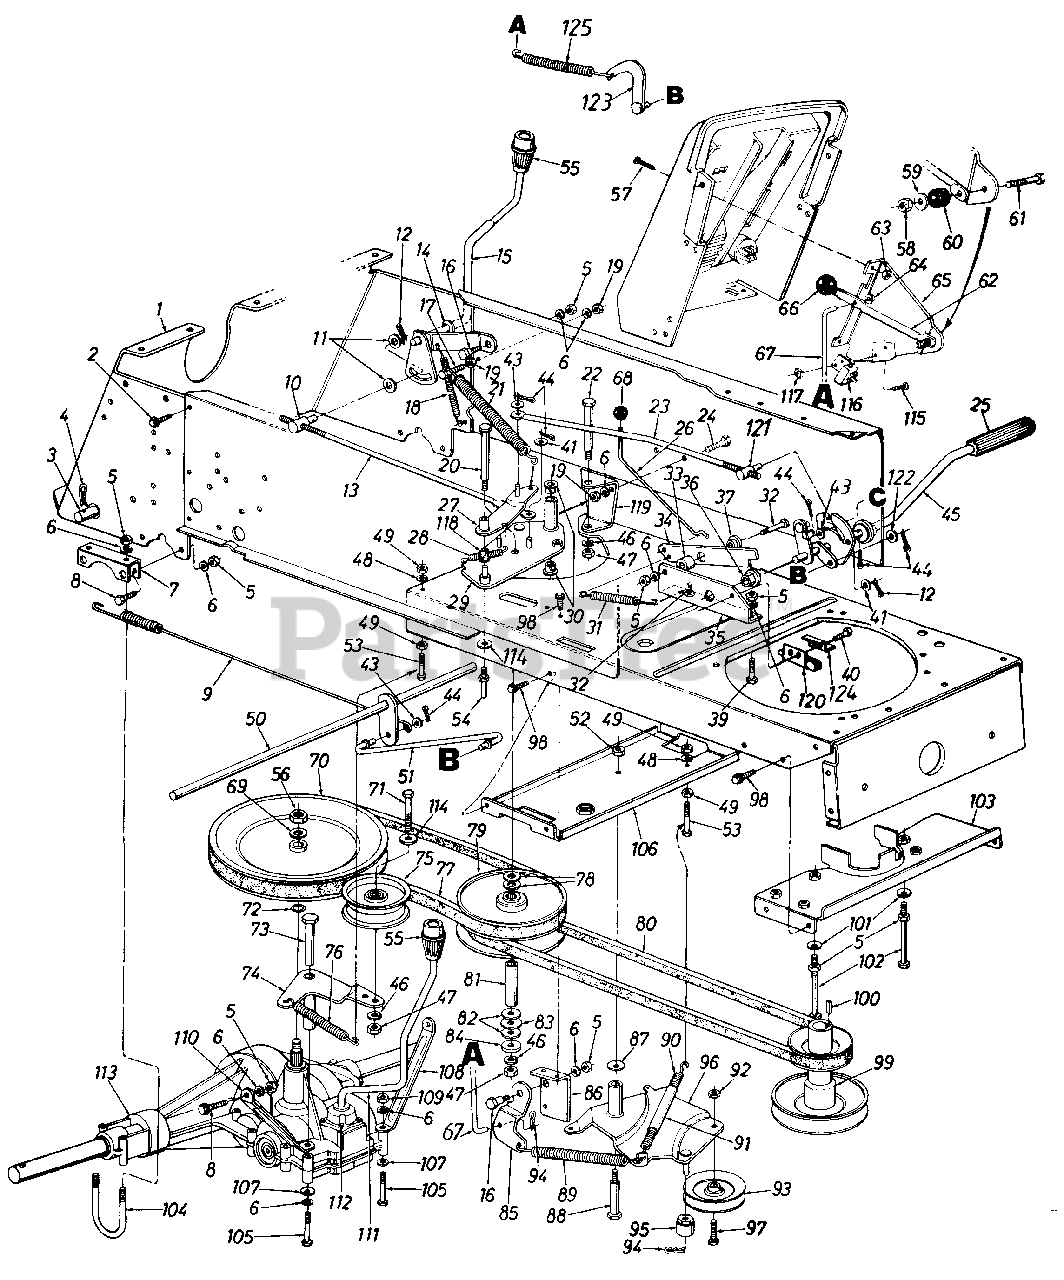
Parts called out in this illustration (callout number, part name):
4	Hitch Pin Clip
5	Hex Nut 5/16-18 Thd.
6	L-Wash. 5/16" I.D.
7	Transaxle Bracket
8	Hex Bolt 5/16-18 x .75" Lg. (Gr. 5)
9	Brake Extension Spring
10	Adjustment Ferrule 3/8-24 Thd.
11	Fl-Wash. .385" I.D. x .87"
12	Internal Cotter Pin
13	Speed Control Link
14	Fl-Wash. .531" I.D. x .94"
15	Speed Selector Lever Ass'y.
16	Shld. Bolt .437" Dia. x .162"
17	Hex Bolt 5/16-24 x 1.25" Lg.
18	Extension Spring 3.9" Lg.
19	Hex Nut 5/16-24 Thd. (Gr. 5)
20	Hex Bolt 3/8-24 x 4.5" Lg.
21	Extension Spring 11" Lg.
22	Shld. Bolt .625n Dia. x 3.5" Lg.
23	Speed Control Link
24	Hex Bolt 5/16-24 x .75" Lg.
25	Foot Pad
26	Parking Brake Link
29	Pulley Plate Ass'y.
30	Flanged Brg. .63" I.D.
31	Extension Spring 2.51" Lg.
32	Hex Bolt 5/16-18 x 1.25" Lg.*
33	Spacer .34" I.D. x .88"
36	Hex Flange Brg. .634" I.D.
37	Shld. Spacer .5" Dia.
39	Hex Bolt 5/16-18 x .75" Lg.
40	Hex Tap Scr. #10-32 x 5/8" Lg.
41	Fl-Wash. .406" I.D. x ,75n O.D.
43	Fl-Wash. .34" I.D. x .68" O.D.
44	Cotter Pin 3/32" Dia.
47	Hex Nut 3/8-24 Thd.
48	L-Wash. 1/4" I.D.
49	Hex Nut 1/4-20 Thd.
50	Brake Link Bracket
51	Front Brake Rod Link
52	Hex Cent. L-Nut 3/8-16 Thd.
53	Hex Bolt 1/4-20 x 2.0" Lg.
54	Belt Guard Pin
56	Hex Jam Nut 9/16-18 Thd.
57	Truss Mach. Scr. 1/4-20 x .5" Lg.
58	Hex Ins. L-Nut 1/4-20 Thd.
59	Fl-Wash. .28" I.D. x .73" O.D.
60	Rubber Washer .33" I.D.
61	Hex Bolt 1/4-20 x 1.25n Lg.
62	Blade Clutch Lever
63	Hex Sems Nut 1/4-20 Thd.
64	Push Nut 1/4" O.D. Rod
65	Deck Clutch Control Brkt.
66	Knob-Blade Clutch
67	Deck Control Rod
68	Ball Knob Brake
69	Bell-Wash. 9/16" I.D. x 1.25"
70	V-Pulley 91/4" O.D.
71	Hex Bolt 3/8-24 x 1.75n Lg.
73	Shld. Bolt 5/16-24 Thd.
74	Idler Brkt. Ass'y.
75	Flat Idler 3.5" O.D.
76	Extension Spring 6.12" Lg.
77	V-Belt
78	Teflon Washer 1.20" O.D.
79	Variable Speed Pulley 5" Dia.
80	V-Belt
81	Pivot Bushing
82	Fl-Wash. .56" I.D. x 1.0" O.D.
83	Thrust Brg. .56" I.D. x 1.25"
84	Retainer Cup
85	Deck Control Pivot Brkt.
86	Parking Brake Mtg. Brkt.
87	Bell-Wash. .88" I.D. x .88" O.D.
88	Shld. Bolt .498" Dia. x 2.05"
89	Extension Spring 6.12" Lg.
90	Extension Spring 5.37" Lg.
91	Convoluted Conduit 4" Lg.
92	Hex Cent. L-Nut 3/8-24 Thd.
93	V-Belt Idler
94	Internal Cotter Pin
95	Spacer
96	Idler Brkt. Deck Ass'y.
97	Hex Bolt 3/8-24 x 1.5" Lg.
98	Hex TT-Tap Scr. 1/4-20 x .5"
99	Engine Pulley
100	Sq. Key 1/4 x 1.5" Lg.
101	Bell-Wash. .345" I.D. x .88n
102	Hex Bolt 5/16-18 x 5.25" Lg.
103	Belt Keeper Brkt. Ass'y.
105	Hex Bolt 5/16-24 x 2.25" Lg.
106	Deck Idler Support Brkt.
107	Fl-Wash. .344" I.D. x .62" O.D.
108	Front Trans. Support Brkt.-L.H.
109	Hex Nut 5/16-24 Thd.*
110	Front Trans. Support Brkt.-R.H.
111	Shift Lever Ass'y. Complete
112	Socket Hd. Cap Scr. #10 x 24
113	2-Speed Transmission Comp.
114	Fl-Wash. 818n l.D. x 1.0n O.D.
115	Truss Mach. Scr. #10-24 x .5"
116	Safety Switch
117	Hex Nut #10-24 Thd.
118	Nyliner Flanged Brg.
119	Variable Speed Support Brkt.
120	Safety Switch
121	Adjustment Ferrule 3/8-24 Thd.
122	Fl-Wash. .344" I.D. x .62n O.D.
123	Foot Pedal Brkt. Ass'y.
124	Switch Plate
125	Ext. Spring 5.2" Lg.
